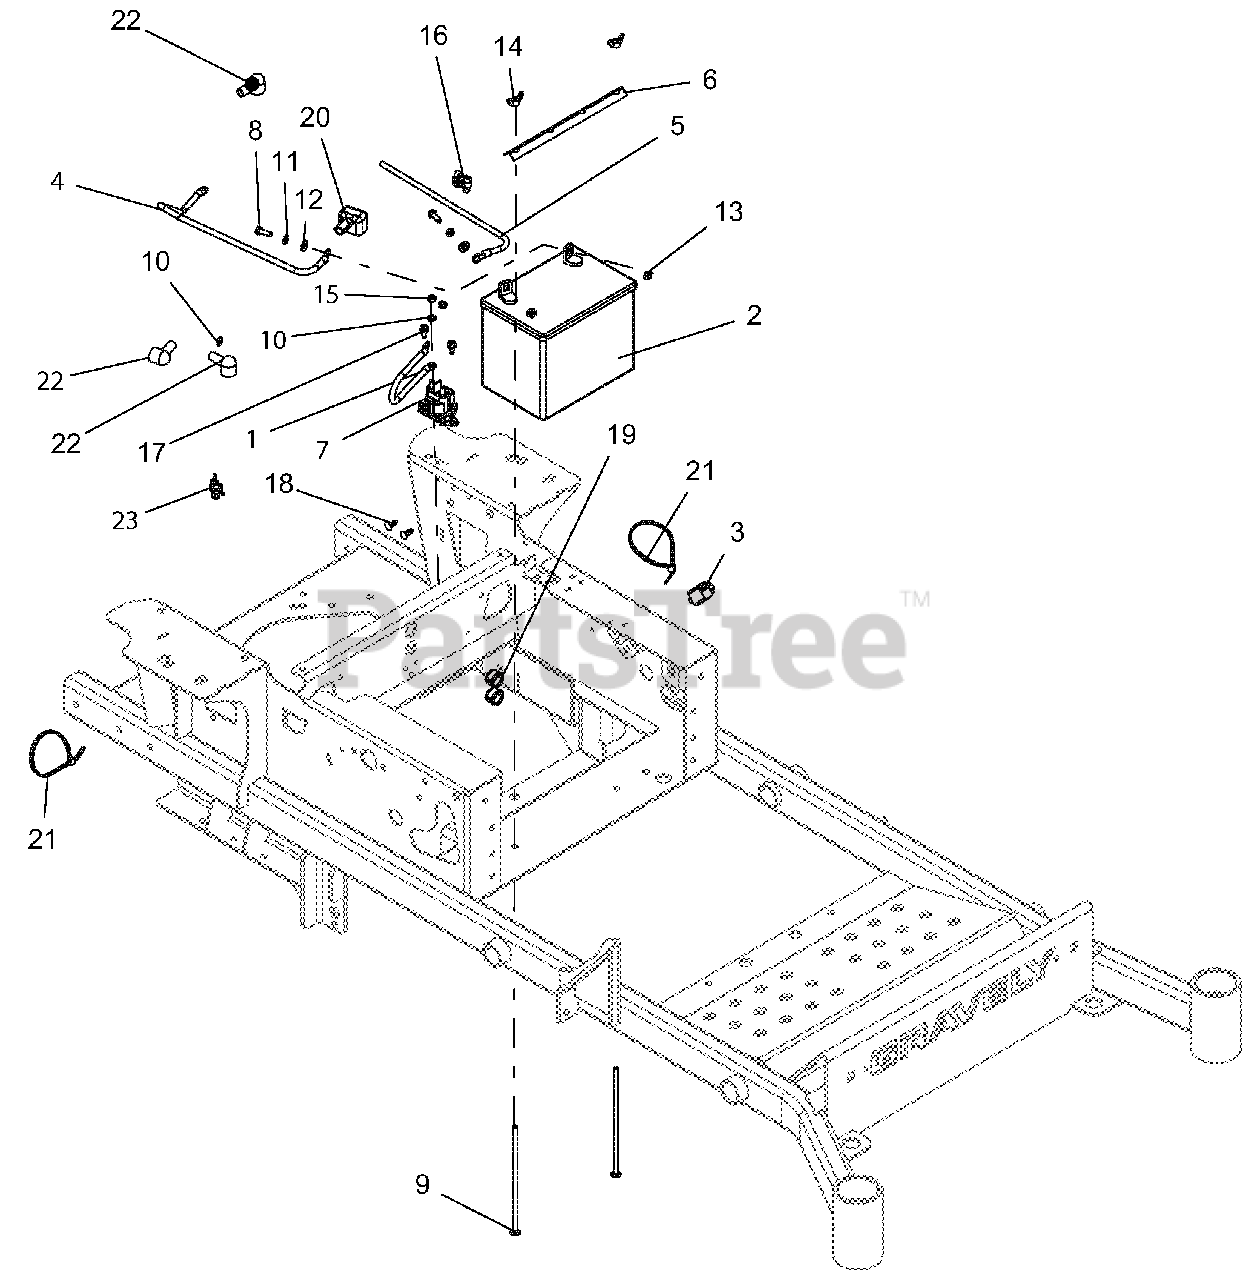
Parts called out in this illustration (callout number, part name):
1	CABLE, POS W/(2) 1/4 RING 9.0 LG
2	BATTERY, 300 CCA 10U1L
3	SWITCH, SINGLE POLE N.O.
4	CABLE, POS W/(2) 1/4 RING 9.0 LG
5	CABLE, NEGATIVE BATTERY 24"
6	HOLD DOWN - BLK
7	SOLENOID, STARTER (SEALED)
8	BLT-HEX .25-20X.75 GR5 YWZC
9	BLT-RDHDSQNK .25-20X7.50 G2 YWZC
10	@, WSHR-LK-EXT.262X.502X.026 YWZC
11	WSHR-LK .25X.062 REG YWZC
12	WSHR-FL-STL.281X.62X.065 YWZC
13	NUT-HEX .25-20 YWZC
14	NUT-LOCKING WING 1/4-20
15	NUT-HEX M6-1.00 YWZC
16	CLIP, T, .318-.3
17	SCR-TAP .25-20X.50 HWH TR YWZ
18	RIVET, .25 NYLON PANEL
19	BUSH, PANEL SNAP .687X.875X.56
20	INSULATOR
21	CABLE, TIE 5.50 LG
22	BOOT, EYELET TERMINAL
